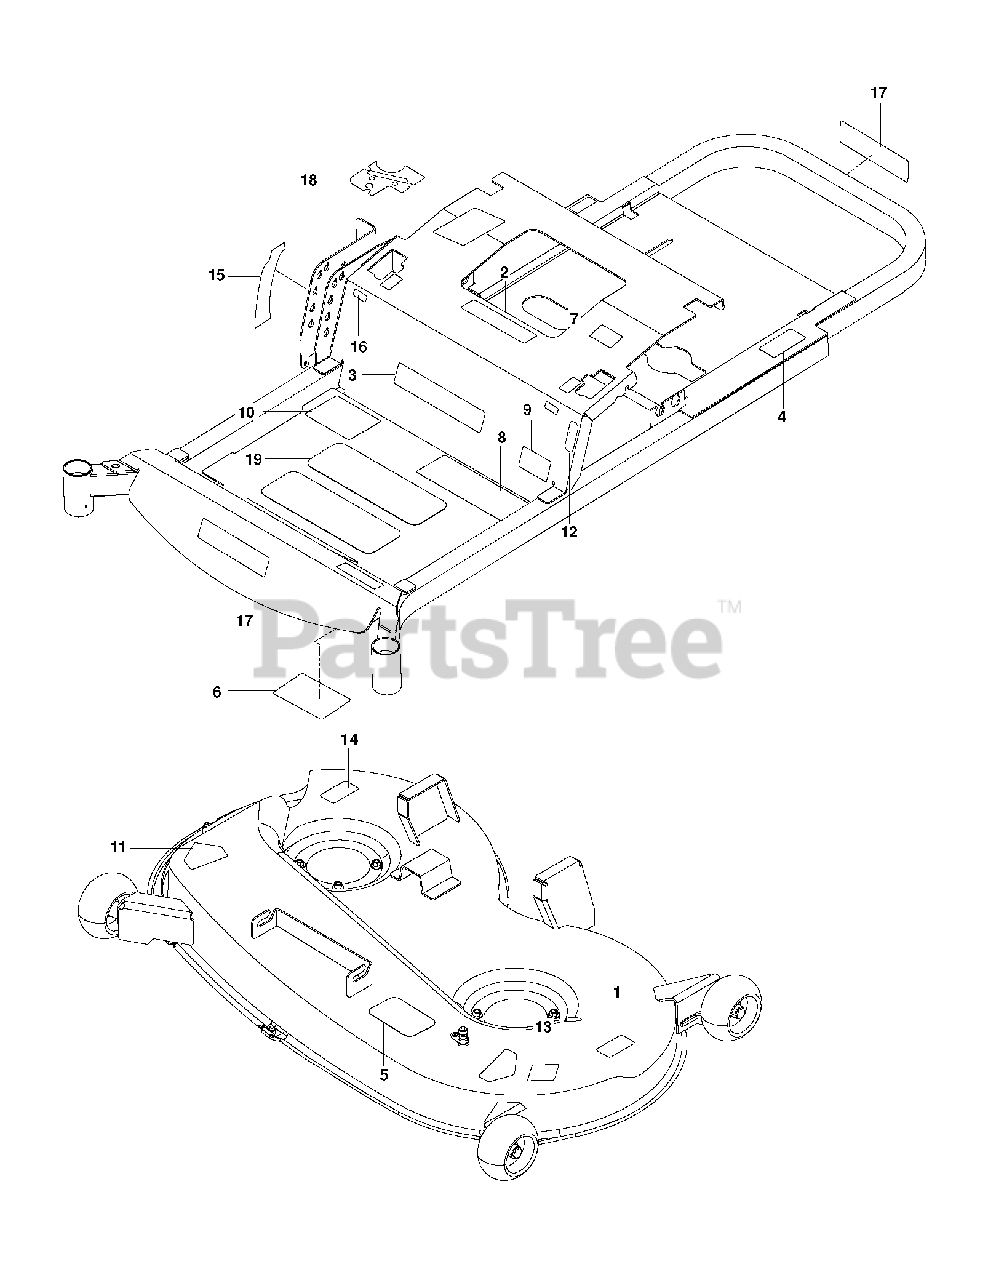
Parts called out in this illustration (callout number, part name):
1	DECAL, 46" WHITE
3	DECAL, SPEEDZTR, 8"
4	DECAL, DO NOT MOUNT
5	DECAL, BELT ROUTING
6	DECAL, SERVICE
7	DECAL, MOTION CONTROL
8	DECAL, SAFETY WARNING
9	DECAL, FLAG
10	DECAL, WARNING
11	DECAL, CPSC
12	DECAL, PARK BRAKE
13	DECAL, EURO SEVERING
14	DECAL, DANGER
15	DECAL, HEIGHT
16	DECAL, TRACKING
18	DECAL, CONTROLS PANEL, DIX
19	ANTI-SKID PAD
